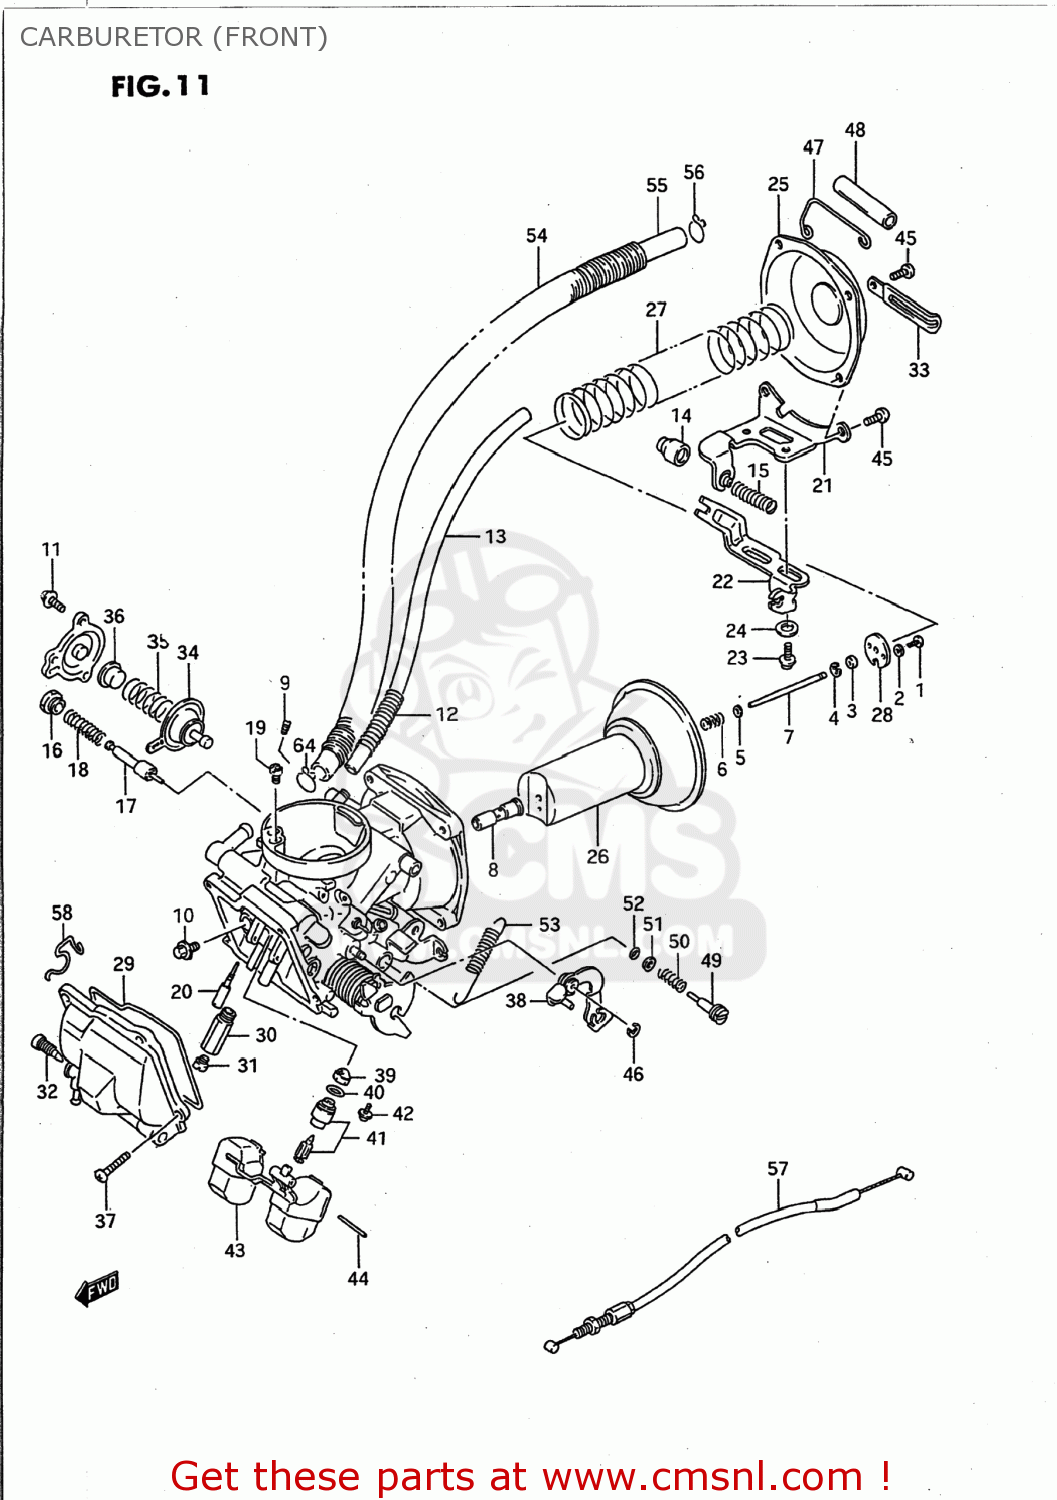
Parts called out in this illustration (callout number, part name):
1	SCREW
2	LOCK WASHER
3	RING
4	CLIP
5	WASHER
6	SPRING
7	NEEDLE JET
8	JET,NEEDLE(O-9)
9	JET,AIR
10	SCREW
11	SCREWM4X0.7X10
12	SPRING
13	HOSE
14	CAP
15	SPRING
16	HOLDER,GUIDE
17	PLUNGER
18	SPRING
19	JET,PILOT
20	JET,PILOT(50)
21	BRACKET
22	PLATE
23	SCREW
24	WASHER
25	COVER,DIAPHRAGM
26	DIAPHRAGM,CARBURETOR
27	SPRING,DIAPHRAGM
28	PLATE
29	O RING,FLOAT CHAMBER
30	HOLDER,MAIN JET
31	JET,MAIN(125)
32	PLUG
33	CLAMP L:35
34	DIAPHRAGM ASSY
35	SPRING
36	PLATE
37	SCREW
38	LEVER,ASSEMBLY
39	FILTER
40	O-RING,NEEDLE VALVE
41	VALVE ASSY,NEEDLE
42	SCREW
43	FLOAT
44	PIN,FLOAT
45	SCREW
46	E-RING
47	CLIP
48	HOSE
49	(CA) HOSE SET,FUEL
50	SPRING
51	CLAMP
52	HOSE
53	HOSE(6.5X11.5X600)
54	CLIP
55	CABLE,IDLE SYNCRO
